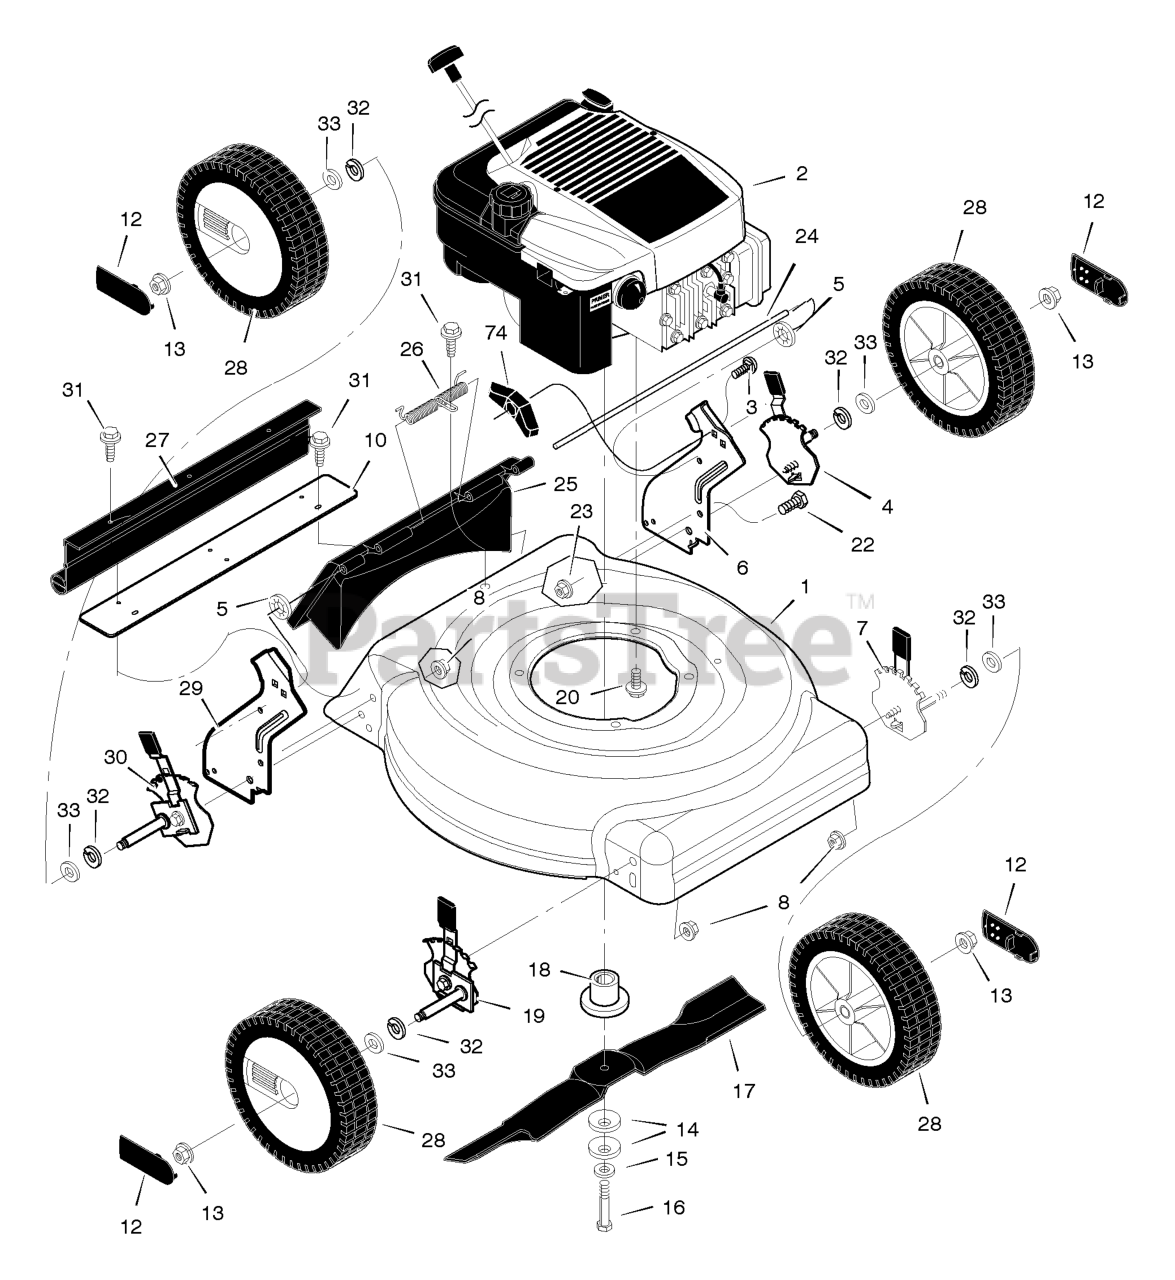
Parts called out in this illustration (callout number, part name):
2	Engine
3	Bolt, Carriage
4	Adjuster, Left Rear Height
5	Push Retainer
6	Bracket, Left Handle
7	Adjuster, Left Front Height
8	Nut, Flange
10	Extension, Rear
12	Hub Cap - Optional
13	Nut, Flange
14	Washer, Belleville
18	Adapter, Blade
19	Adjuster, Right Front Height
20	Bolt, Engine
22	Bolt
23	Nut, Flange
24	Rod, Pivot
25	Door, Rear
27	Guard, Rear
29	Bracket, Right Handle
30	Adjuster, Right Rear Height
